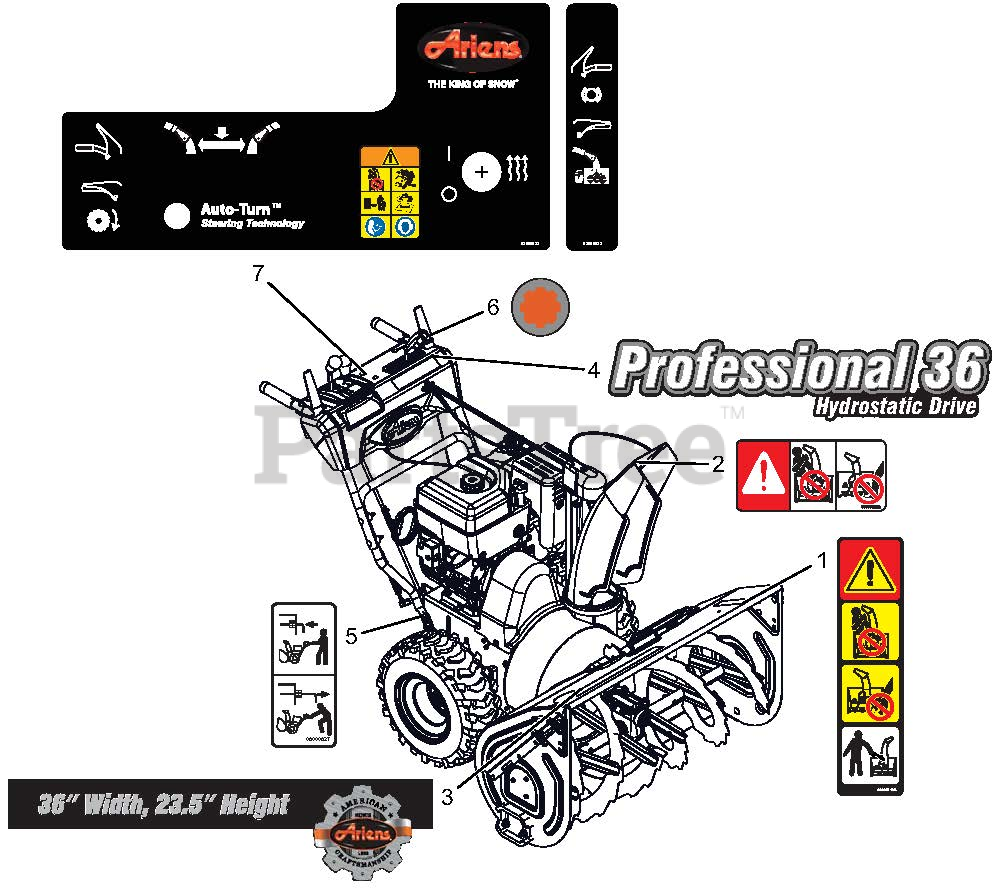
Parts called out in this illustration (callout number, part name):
1	DECAL, DANGER - ROTATING PARTS
2	DECAL, DANGER
4	DECAL, PRO HYDRO 36 DASH
5	DECAL, BYPASS
6	DECAL,AUTODIFFERENTIAL
7	DECAL,CONTROL-LRG,QT2
